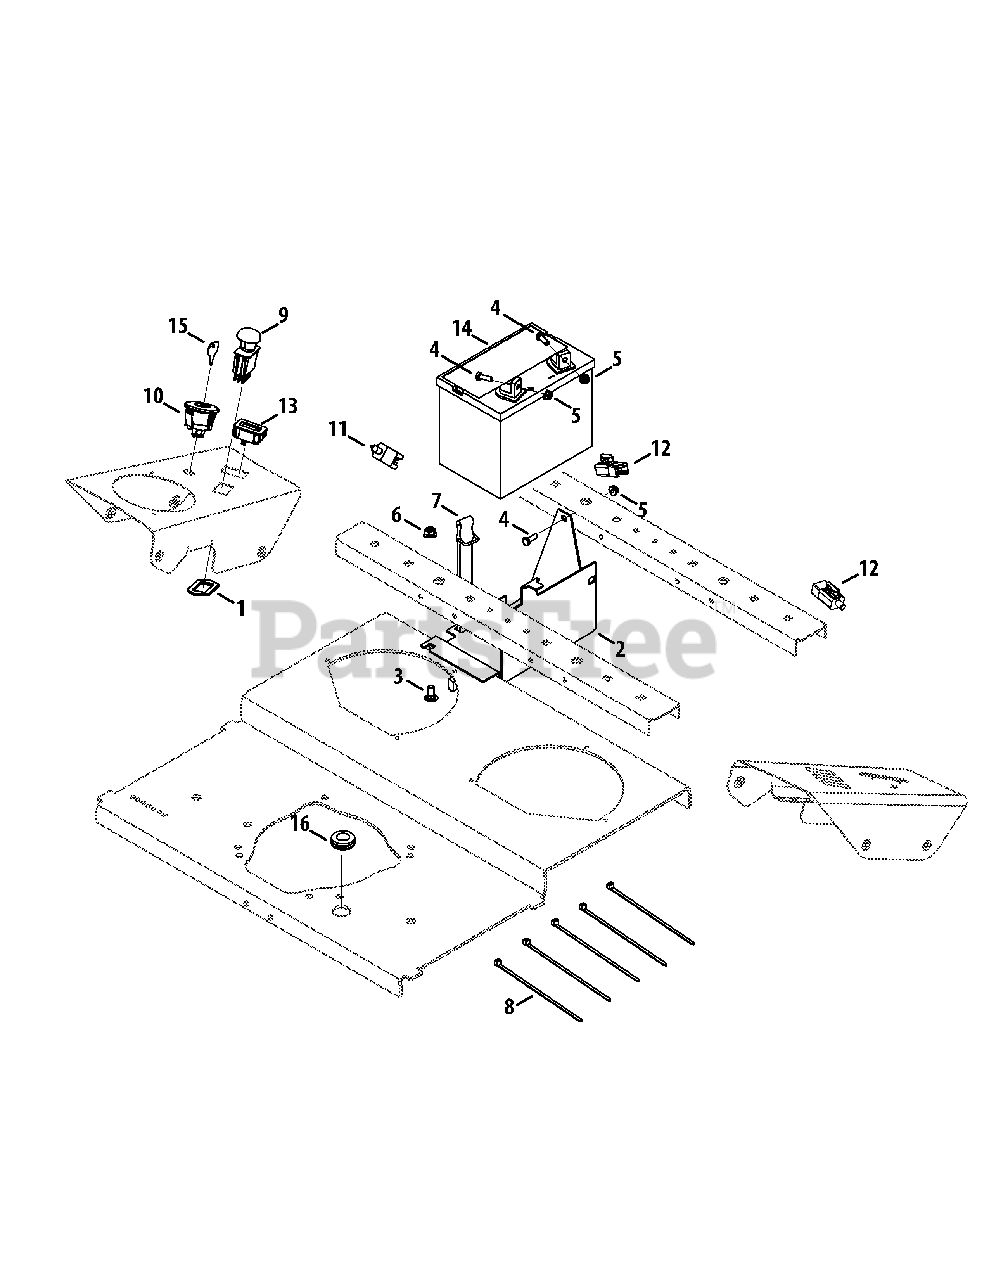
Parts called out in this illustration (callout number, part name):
1	PTO Switch Bracket
2	Battery Bracket
3	Carriage Bolt, 3/8-16 x .750
4	Hex Cap Screw, 1/4-20 x .75
5	Nut, 1/4-20, Flangelock
6	Nut, 3/8-16, Flangelock
7	Battery Strap
8	Cable Tie
9	Electric PTO Switch
10	Key Switch
11	Switch, NC/NO/NO
12	Plunger Switch, NO/NC
13	Hour Meter
15	Key
16	Rubber Grommet, .75 x 1.062 x .50
